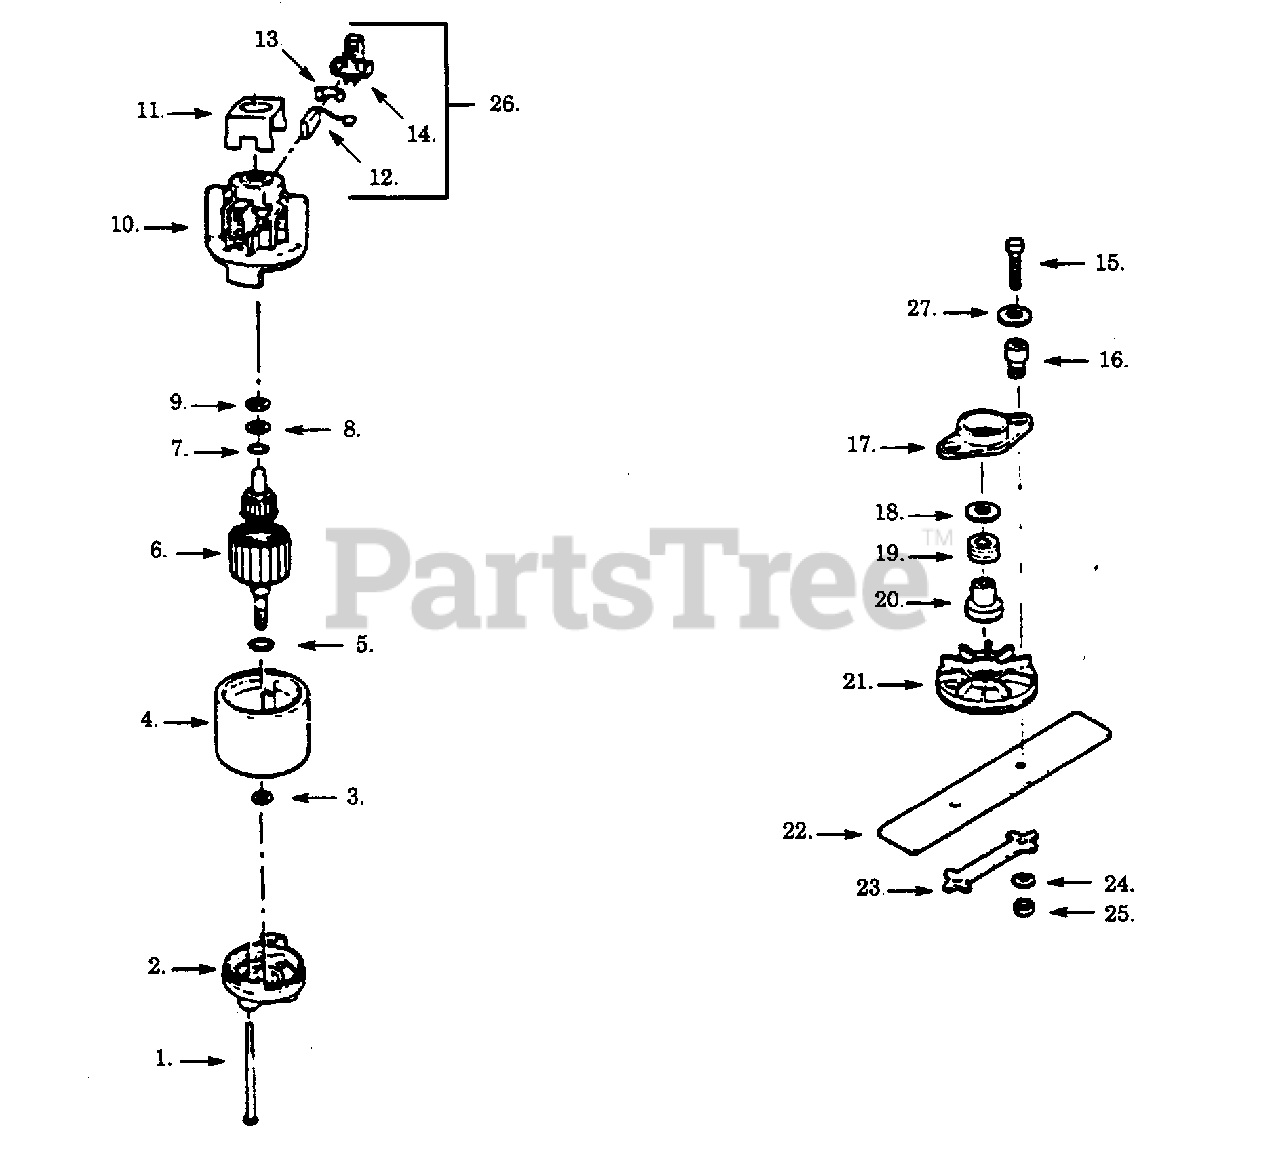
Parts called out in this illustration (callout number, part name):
2	Endbell Ass'y. (Drive)
4	Field Ass'y.
5	Retaining Ring
6	Armature Ass'y.
7	Retaining Ring
10	Endbell Ass'y. (Brush)
11	Insulator
13	Brush Spring
14	Brush Holder
17	Clutch Plate
19	Spring Washer
20	Clutch Sleeve
23	Lockstrap
24	Lockwasher
26	Brush Kit (Inc. 12,13,14)
27	Thrust Washer
